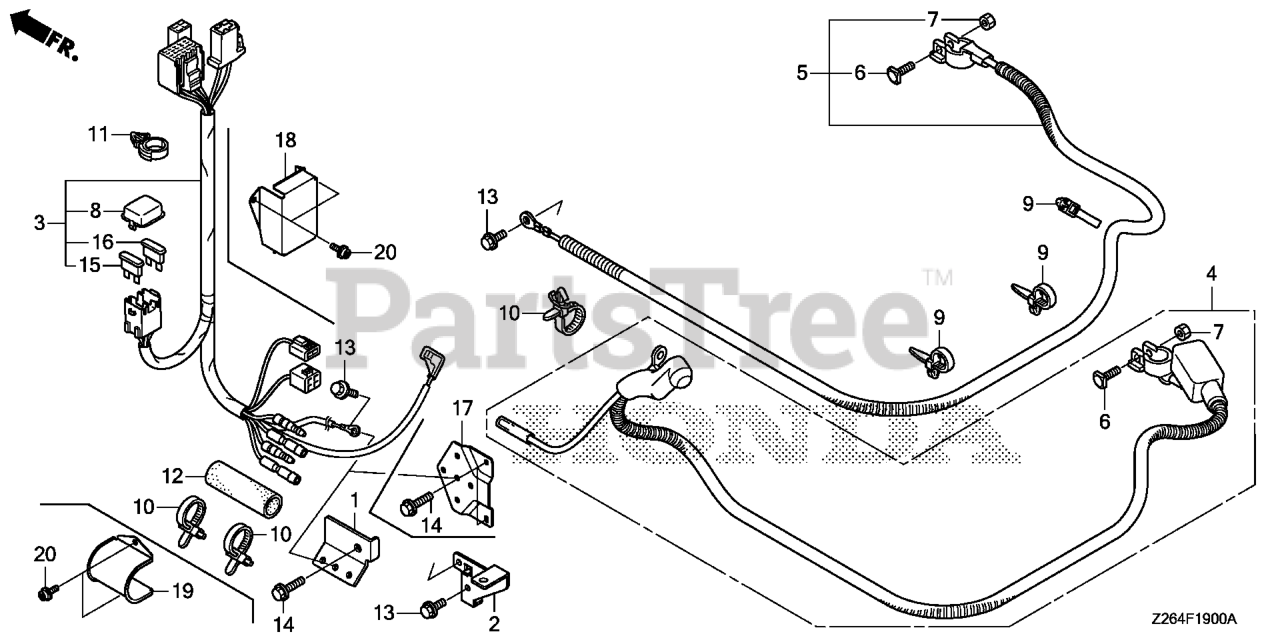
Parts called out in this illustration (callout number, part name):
1	BRACKET, WIRE HARNESS CLIP (A)
2	BRACKET, WIRE HARNESS CLIP (B)
3	WIRE HARNESS ASSY., ENGINE
4	CABLE ASSY., STARTER
5	CABLE ASSY., GROUND
6	BOLT, BATTERY TERMINAL
7	NUT, BATTERY TERMINAL
8	CASE, FUSE (2P)
9	TIE, CABLE
10	BAND, WIRE HARNESS
11	CLIP, WIRE HARNESS
12	TUBE, CORD
13	BOLT, FLANGE (6X10)
14	BOLT, FLANGE (6X20)
15	FUSE, BLADE (5A)
16	FUSE, BLADE (20A)
